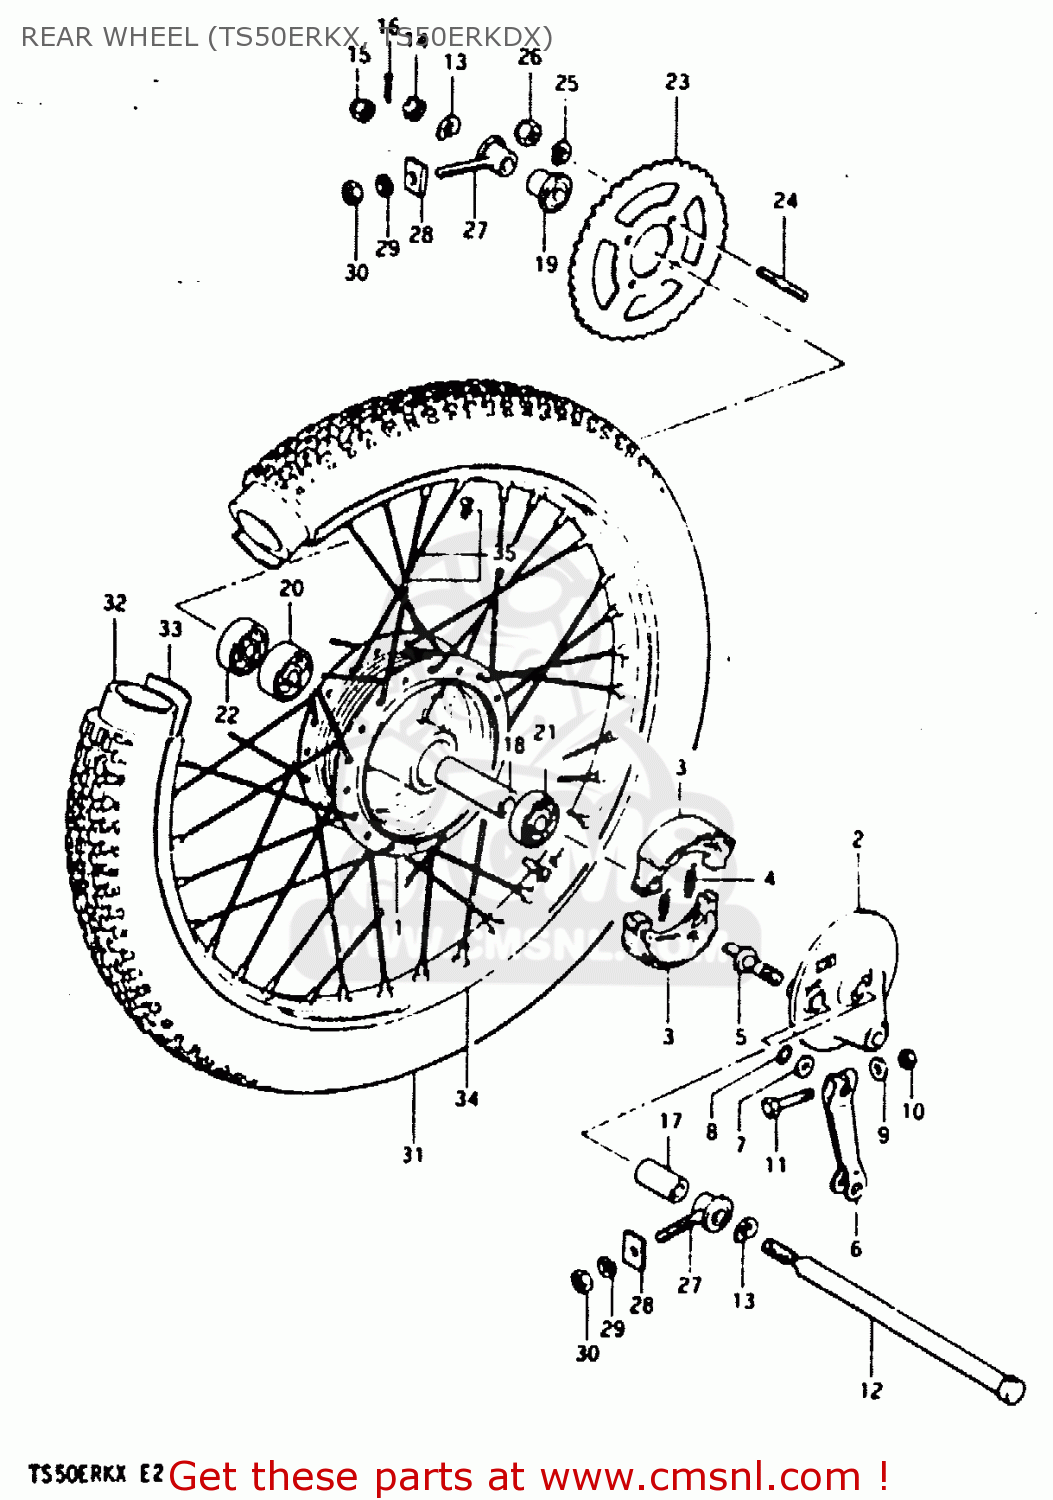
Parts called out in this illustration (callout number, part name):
1	DRUM SET,REAR HUB
2	PANEL,REAR BRAKE ANCHOR
3	SHOE,BRAKE (MCA)
4	SPRING(L:34)
5	CAM,FRONT BRAKE
6	LEVER,RR BRAKE CAM
7	WASHER (14.5X22X1.6)
8	O-RING (D:2.4 ID:13.8)
9	WASHER
10	NUT
11	BOLT(6X33)
12	AXLE,RR
13	WASHER,RR AXLE
14	NUT 12MM
16	COTTER PIN
17	SPACER, AXLE RH
18	SPACER (12.6X19X79)
19	SPACER, REAR AXLE LH
20	BEARING
21	BEARING
22	BEARING
23	SPROCKET, REAR (NT:49)
24	BOLT
25	LOCK WASHER
26	NUT
27	ADJUSTER, CHAIN
28	ADJUSTER,CHAIN
29	LOCK WASHER
30	NUT
31	TIRE
32	TUBE,INNER
33	PROTECTOR,INNER TUBE
34	RIM, WHEEL
35	SPOKE SET,REAR WHEEL
